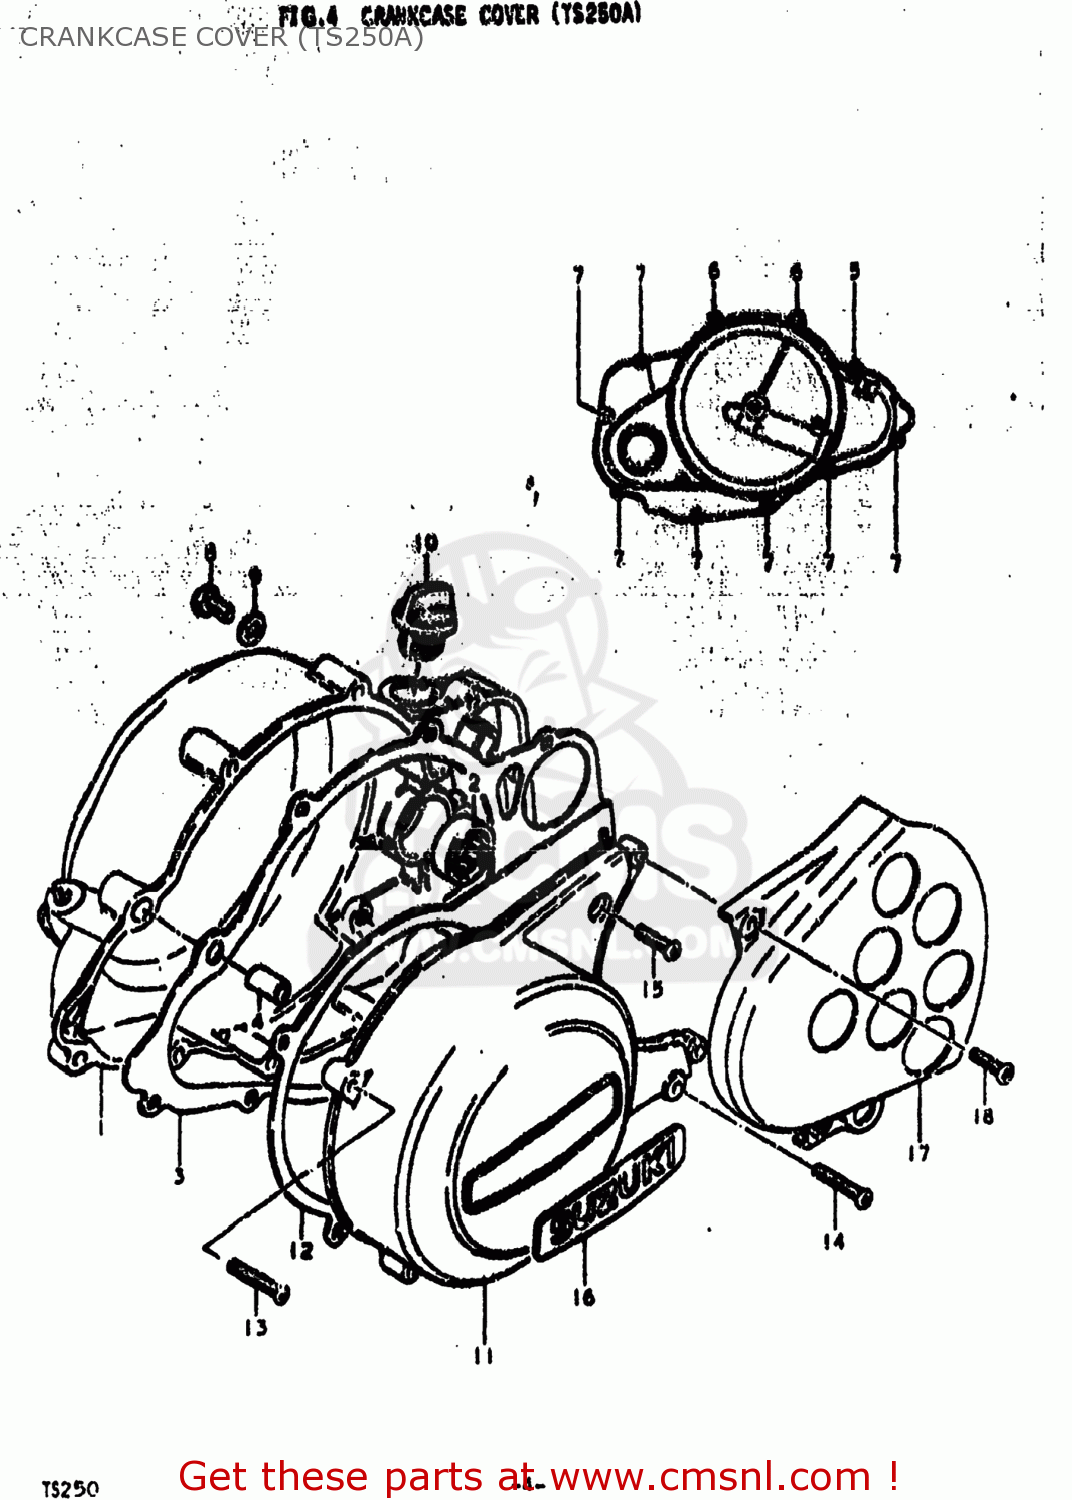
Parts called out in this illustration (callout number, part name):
1	CRANKCASE SET
2	BEARING
3	GASKET,CLUTCH COVER (AS (MCA)
4	PIN
5	SCREW (6X45)
6	SCREW (6X35)
7	SCREW
8	SCREW(6X10)
9	GASKET(6.2X11X1) (NAS)
10	PLUG
11	COVER,MAGNETO
12	GASKET,MAGNETO COVER (NAS)
13	SCREW
14	SCREW
15	SCREW
16	EMBLEM,MAGNETO COVER
17	COVER,SPROCKET
18	SCREW
